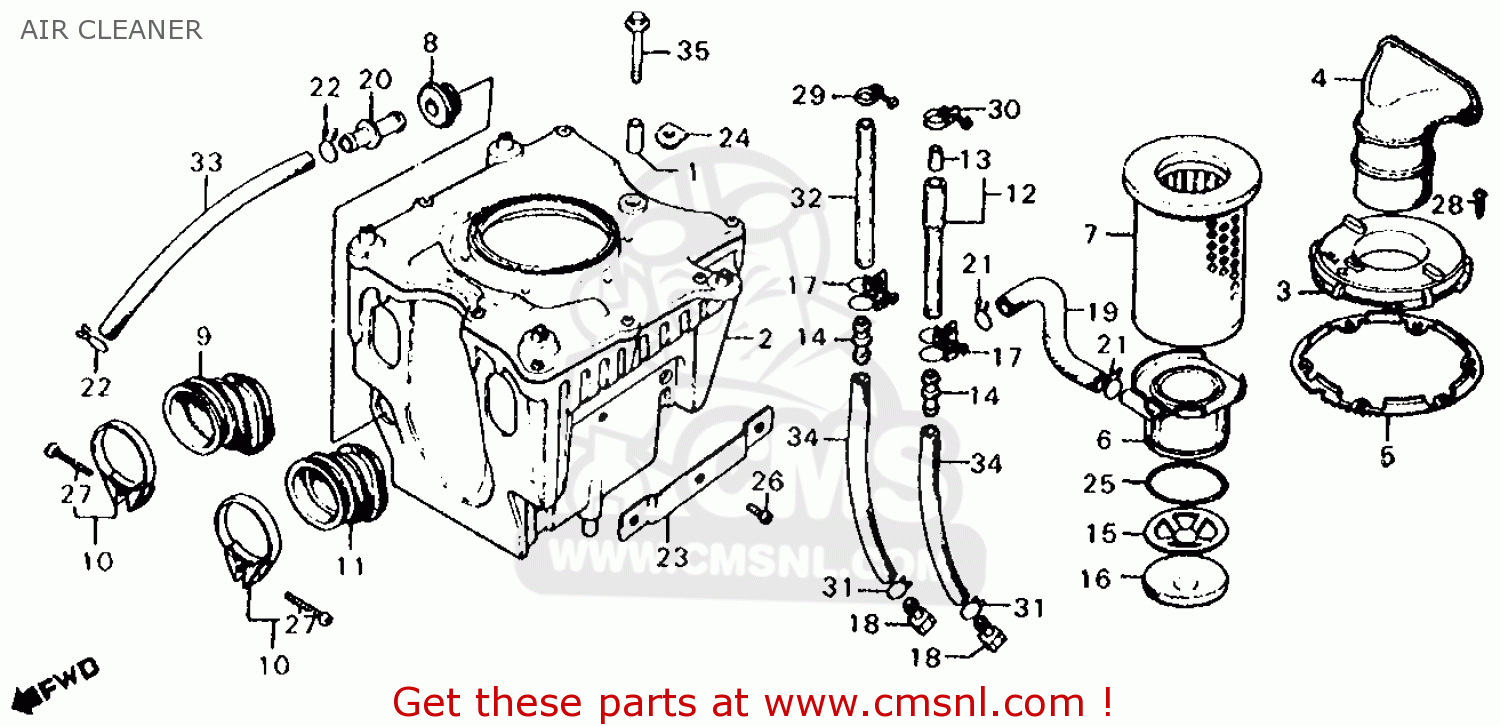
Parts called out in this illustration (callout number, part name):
1	COLLAR,CLEANERBCT
2	CASE COMP., AIR/C
3	CAP,CLEANER ELEME
4	TUBE,CLEANER DUCT
5	HOLDER,CAP
6	HOLDER,ELEMENT
7	ELEMENT CLEANER
8	GROMMET, TUBE
9	TUBE,R.CONNECTING
10	BAND B,CONN.TUBE
11	TUBE,L.CONNECTING
12	TUBE, BREATHER
13	FILTER
14	JOINT,TUBE
15	SEPARATOR A
16	ELEMENT,SEPARATOR
17	CLIP A13.5,TUBE
18	PLUG,BRTHR TUBE
19	TUBE, BREATHER
20	JOINT,BREATHER
21	CLIP,TANK HOSE
22	CLIP, AIR HOSE 16MM
23	PLATE,BATTERY
24	PATCH,RR.COWL
25	O-RING,63.5X2.0
26	SCREW,PAN,4X8
27	SCREW,PAN,4X20
28	SCREW,TAPPING,4X8
29	CLIP A12,TUBE
30	CLIP, TUBE, A15
31	CLIP,TUBE,B12.5
32	BULK HOSE, VINYL
33	BULK TUBE,TB 12X1
34	BULK TUBE,TB 80X1
35	BOLT,FLANGE,6X35
